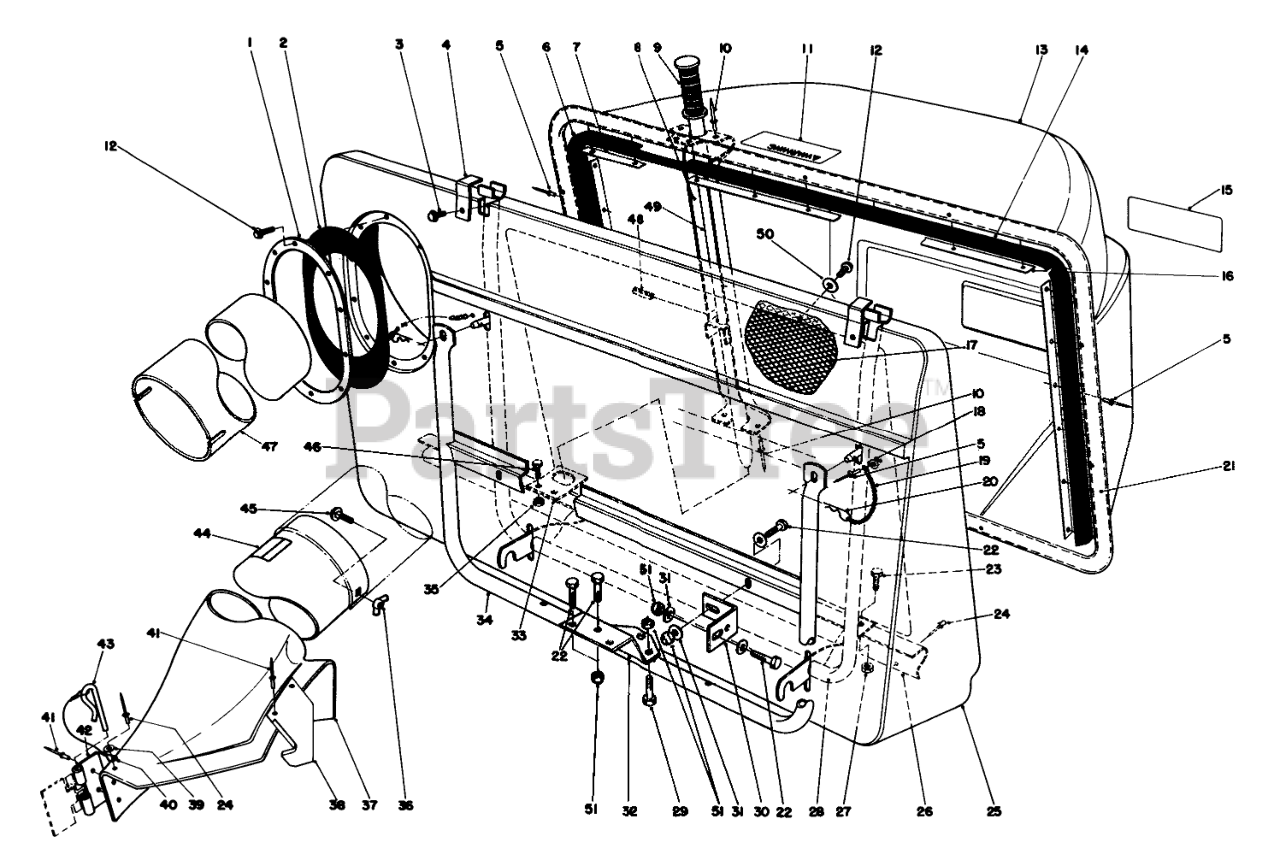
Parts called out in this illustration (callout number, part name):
1	RING-RETAINING
2	RING-RETAINER, RUBBER
3	SCREW-HWH
4	RETNR PIVOT BRKT
6	RH BAG SEAL
7	RETNR TOP EXT.
8	DUMP HDLE CHANL WA
11	Decal Warning
12	SCREW-HWHTF
13	REAR GRASS BASKET
14	Seal-Bag LH.
15	EASY EMPTY BAG DECAL
16	BAG RETNR EXT.
17	Screen Bag
18	WASHER
19	10 LINK CHAIN W/O HOOK
20	PIN-HAIR
21	BAG SUPT ASM FRM
22	SCREW-HH
23	SCREW-HH
24	RIVET-BLIND
25	Bag Front
26	FRAME SUPT BRKT B
27	NUT-LOCK, CONE
28	Bag Frame
29	SCREW-HH
30	MTG BRACKET
31	WASHER-PLAIN
32	MTG PLATE B
33	Hanger-Frame Lower
34	BAG SUPPORT WA
35	NUT-LOCK, CONE
36	NUT-WING SPECL
37	Chute Assembly (Incl. Ref. #24, 38-44)
38	CHUTE SUPT BRKT
39	WASHER-PLAIN
40	LANYARD
41	RIVET-BLIND
42	BRACKET-MOUNTING, CHUTE
43	PIN-LOCKING, CHUTE
44	DECAL-DANGER
45	BOLT-CARR
46	SCREW-HH
47	TUBE(ROUND&LONG)
48	PIN-ROLL
49	DUMP HANDLE ASM
50	WASHER-FLAT
51	NUT-LOCK, NI
